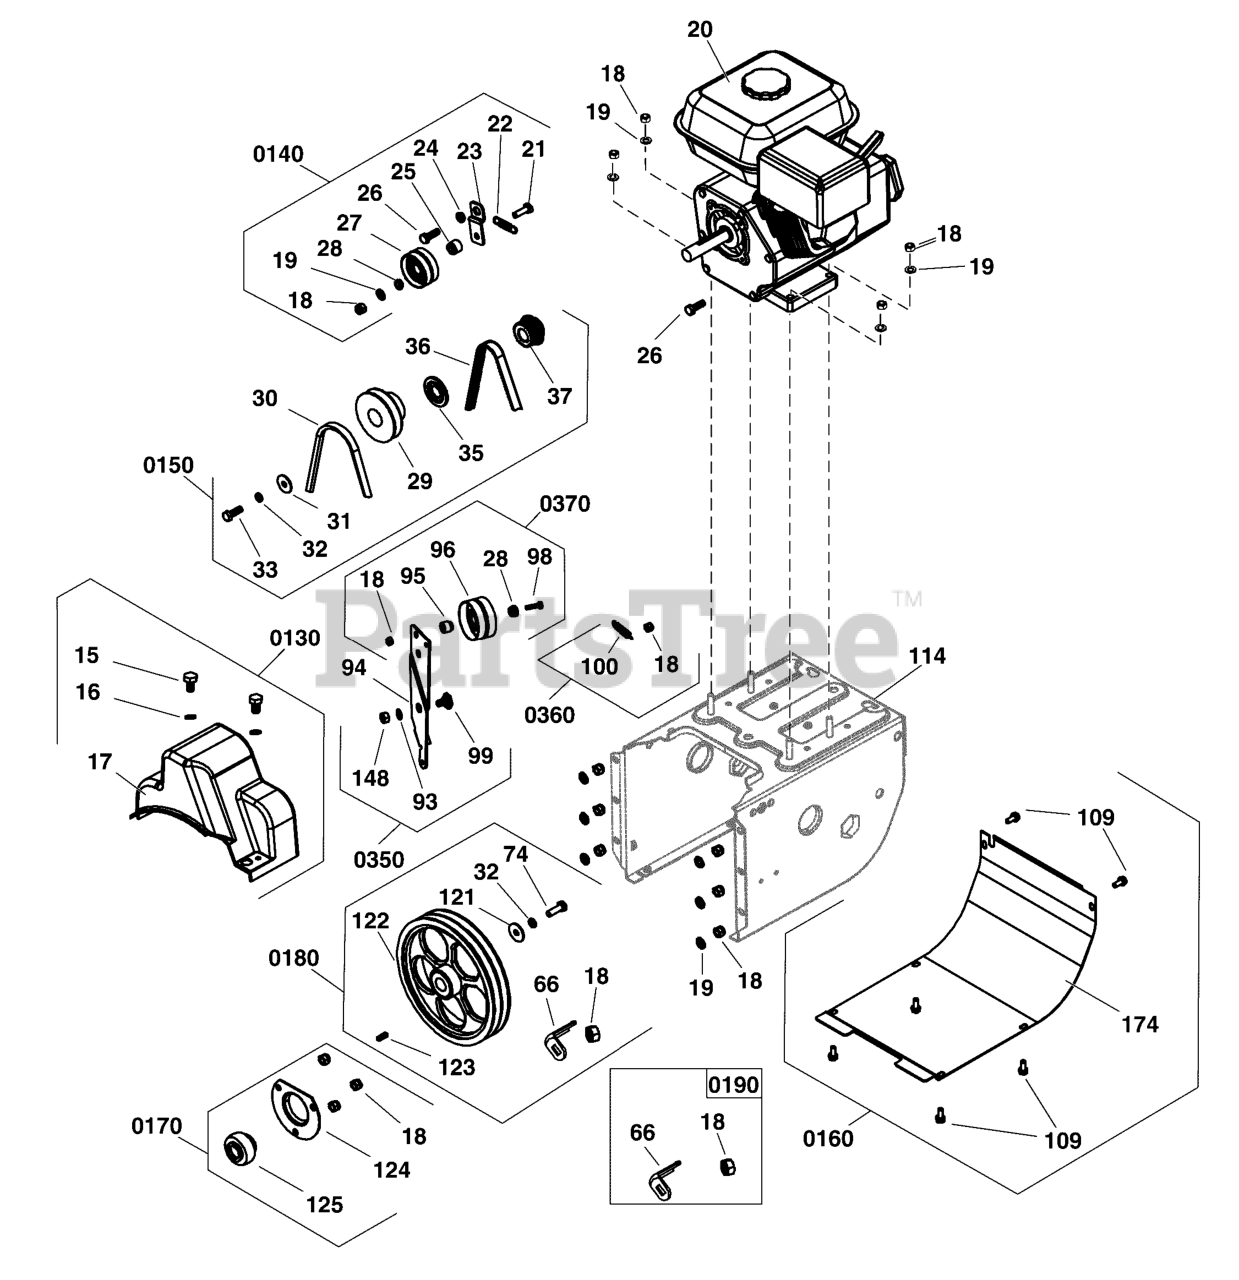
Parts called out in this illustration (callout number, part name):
15	*SCREW, Hex Head
16	*WASHER, Flat
17	*COVER, Belt
18	*NUT, Hex Head Lock, Non-metal
19	*WASHER, Flat
20	ENGINE, 11.5 Gross TP Briggs & Stratton
21	*SCREW, Hex Head
22	SPRING
23	*PLATE, Tensioning, Small
24	*PAD, Tensioning Plate, Small
25	*PAD, Tensioning Wheel, Small
26	*SCREW, Hex Head
27	*WHEEL, Tensioning Assembly, Small
28	*Washer
28	*WASHER
29	*PULLEY, Impeller Drive
30	BELT, Auger Drive
31	*WASHER, Flat
32	*WASHER, Spring
33	*SCREW, Hex Head
35	*RING, Retainer, Synch-pulley
36	BELT, Traction Drive
37	*SYNCH-PULLEY
66	*BAFFLE, Belt
74	*SCREW, Hex Head
93	*WASHER, Flat
94	IDLER, Auger
95	*SLEEVE, Washer
96	*WHEEL, Large Tensioning
98	*SCREW, Hex Head
99	*SCREW, Hex Head
100	*SPRING
109	*SCREW, Hex Head
114	*BOX, Frame
121	*WASHER, Flat
122	*PULLEY, Drive
123	*KEY, Flat
124	RETAINER, Ball Bearing
125	BEARING, Ball
0130	KIT, Belt Cover
0140	KIT, Idler Pulley, Traction Drive
148	*NUT, Hex Head Lock, Non-metal
0150	KIT, Engine Pulley
0160	KIT, Bottom Cover
0170	KIT, Bearing Hardware, Auger Pulley
174	*COVER, Motor Box, Lower
0180	KIT, Auger Pulley
0190	KIT, Belt Guide, Auger
0350	KIT, Hardware, Idler Bracket
0360	KIT, Spring, Idler Pulley
0370	KIT, Idler Pulley, Tension Plate
